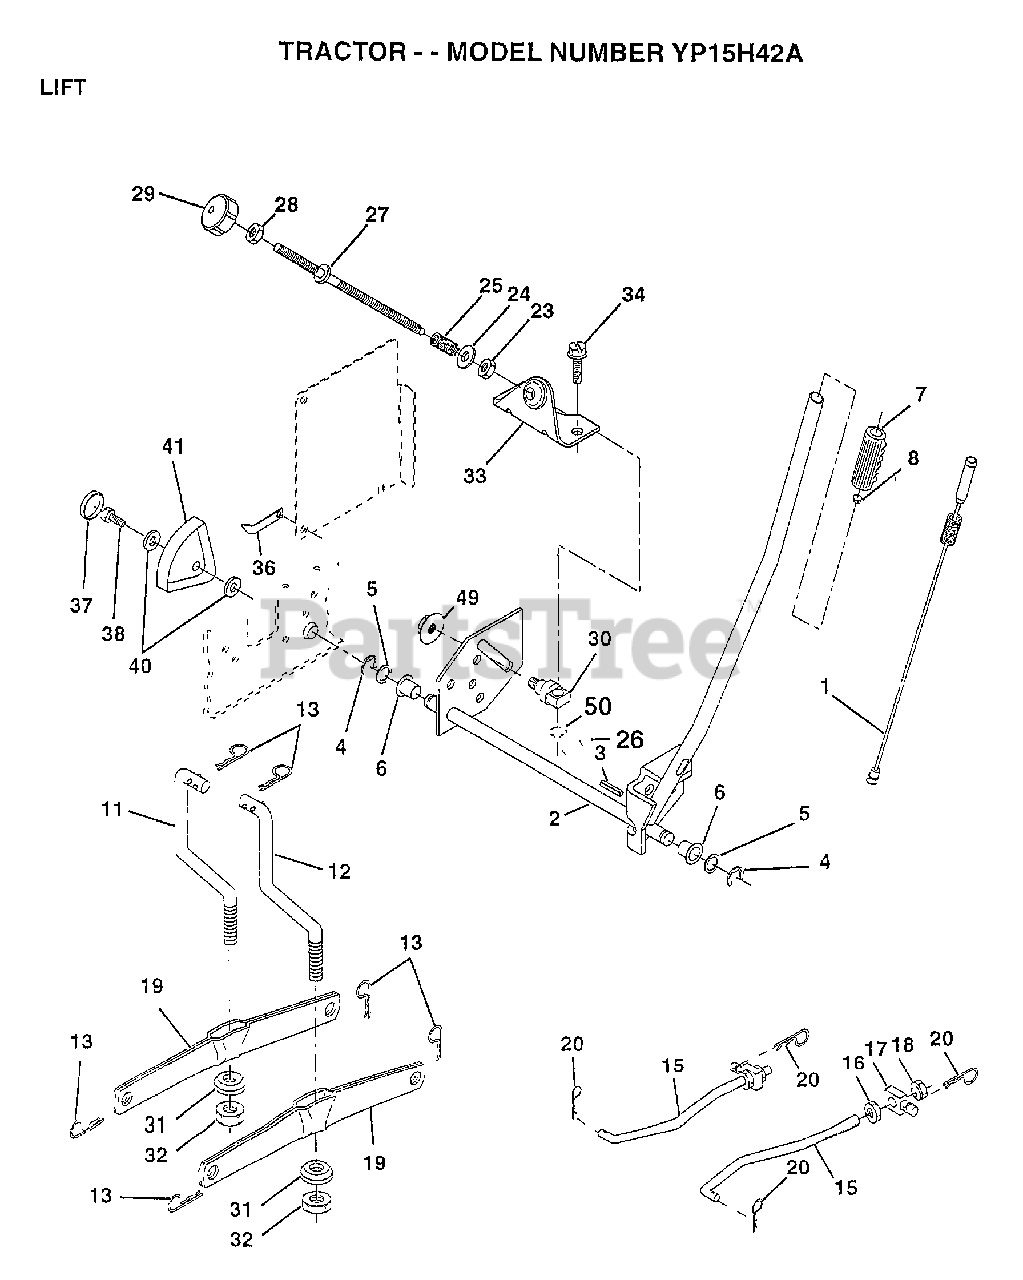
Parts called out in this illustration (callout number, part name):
1	WIRE ASM W.SPRING
2	SHAFT ASM LIFT RH
3	PIN-GROOVE LT
5	WASHER
6	NYLON BEARING
7	GRIP HANDLE
15	LINK.FRONT
16	NUT
17	TRUNION
18	NUT.LK.W/WSH.1/2.
19	ARM SUSP REAR
20	RETAINER.SPRING
23	NUT T
24	WASHER
25	SPRING T
28	NUT
29	KNOB INF 3/8-16
30	TRUNNION
31	BEARING PVT LH
32	NUT.CROWNLOCK.3/8
33	BRACKET STOP INF
34	SCREW LT
36	POINTER-INDICAT
37	"PLUG,HOLE"
38	SCREW
40	WASHER
41	HEIGHT INDICATOR
49	NUT.HXFLG.LOCK.
50	NUT PUSH M
